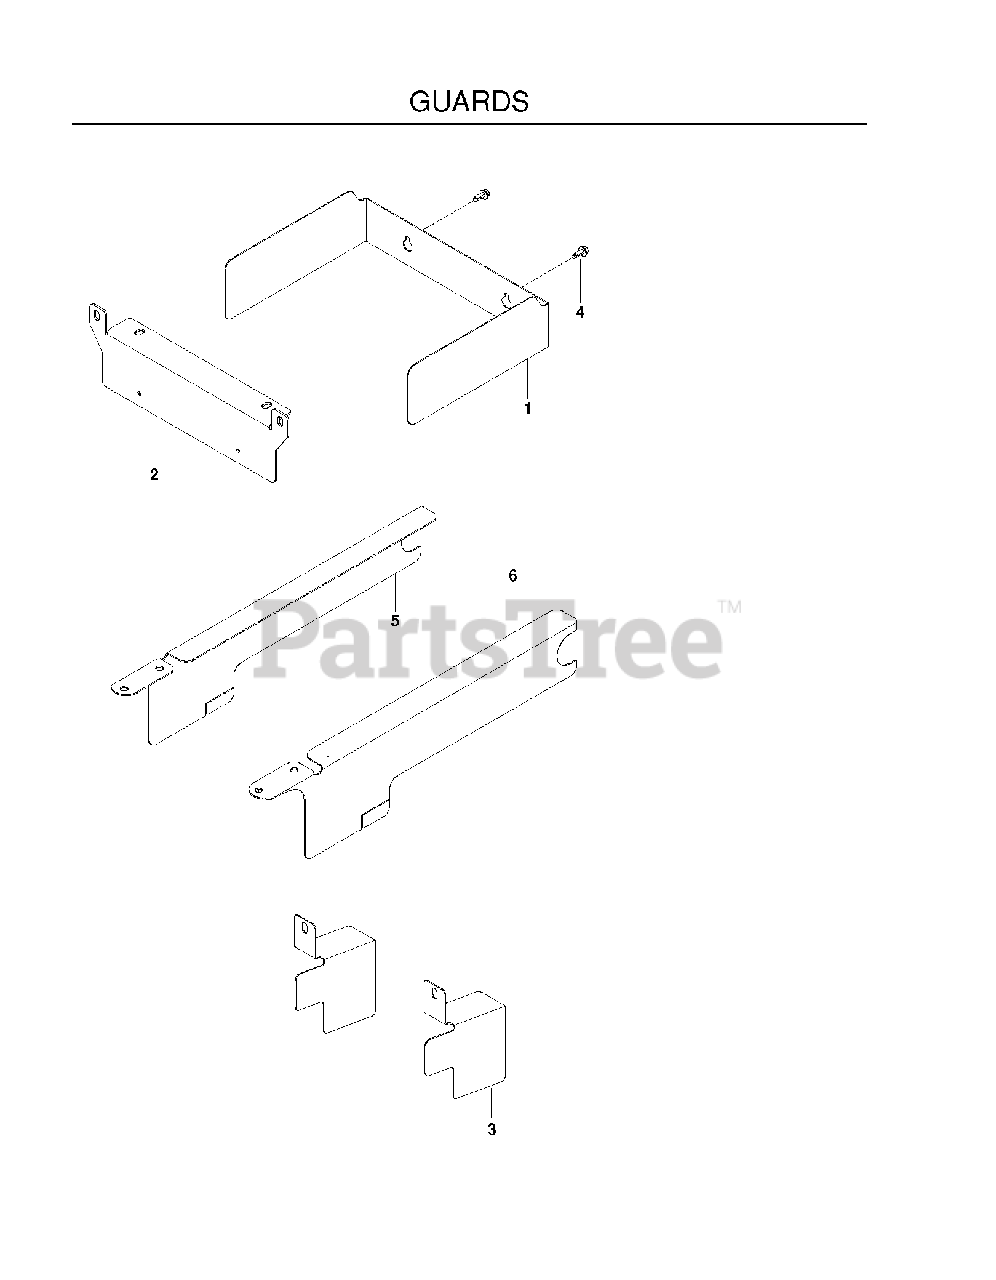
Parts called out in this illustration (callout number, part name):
1	BRACKET.GUARD.PZ.CLUTCH
2	GUARD.PZ.CLUTCH.BLK
3	GUARD.PZ.MIDSECTION.BL
4	SCREW- 1/4-20 X 5/8
5	SKIRT.RH.BLK
6	SKIRT.LH.BLK
